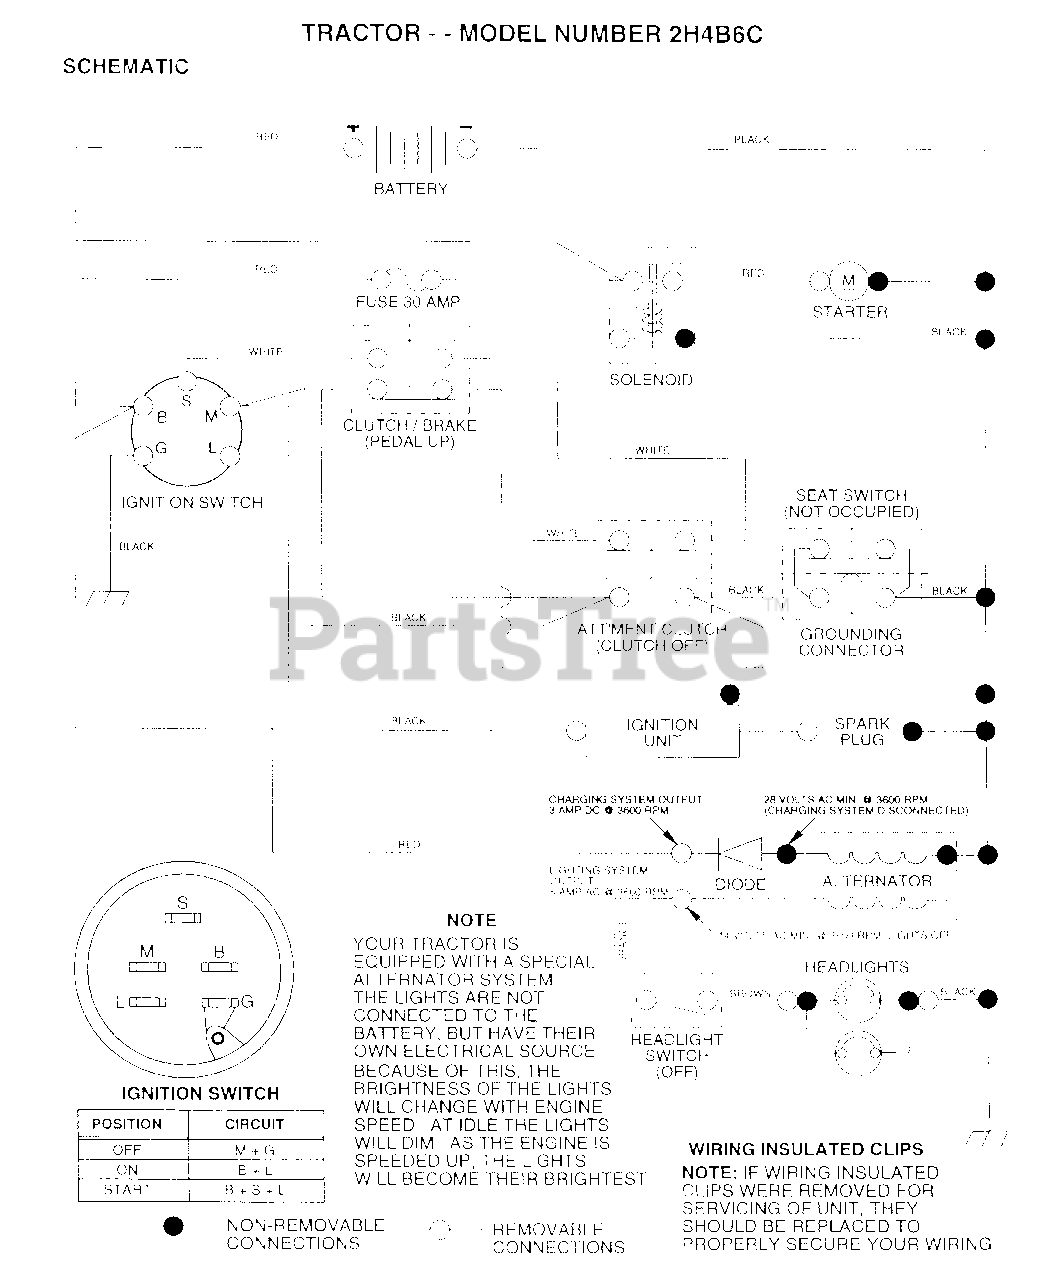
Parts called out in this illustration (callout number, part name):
2	BOLT LT
3	WASHER
4	LOCKWASHER
7	TUBE T
9	HOSE CLAMP T
15	FASTNER.SNAP-IN
20	NUT
21	"HARNESS,LIGHT SOC"
22	HEADLAMP BULB
24	"CABLE T, BATTERY"
25	CABLE.BTRY.6GA.RD
26	FUSE HYT
28	CABLE T
29	SWITCH SEAT
32	COVER KEY SWITCH
33	KEY MLD GEN DELTA
34	SWITCH LT
35	BRACKET LT
36	SCREW
38	BRACKET SWITCH IN
39	SWITCH INTERLOCKT
40	HARNESS.IGN.DASH.
41	BOLT HXHD FIN
44	NUT HXKEP 1/4X20
48	ADAPTER AMMETER
49	LOCKWASHER
70	HARNESS ENG DUAL
